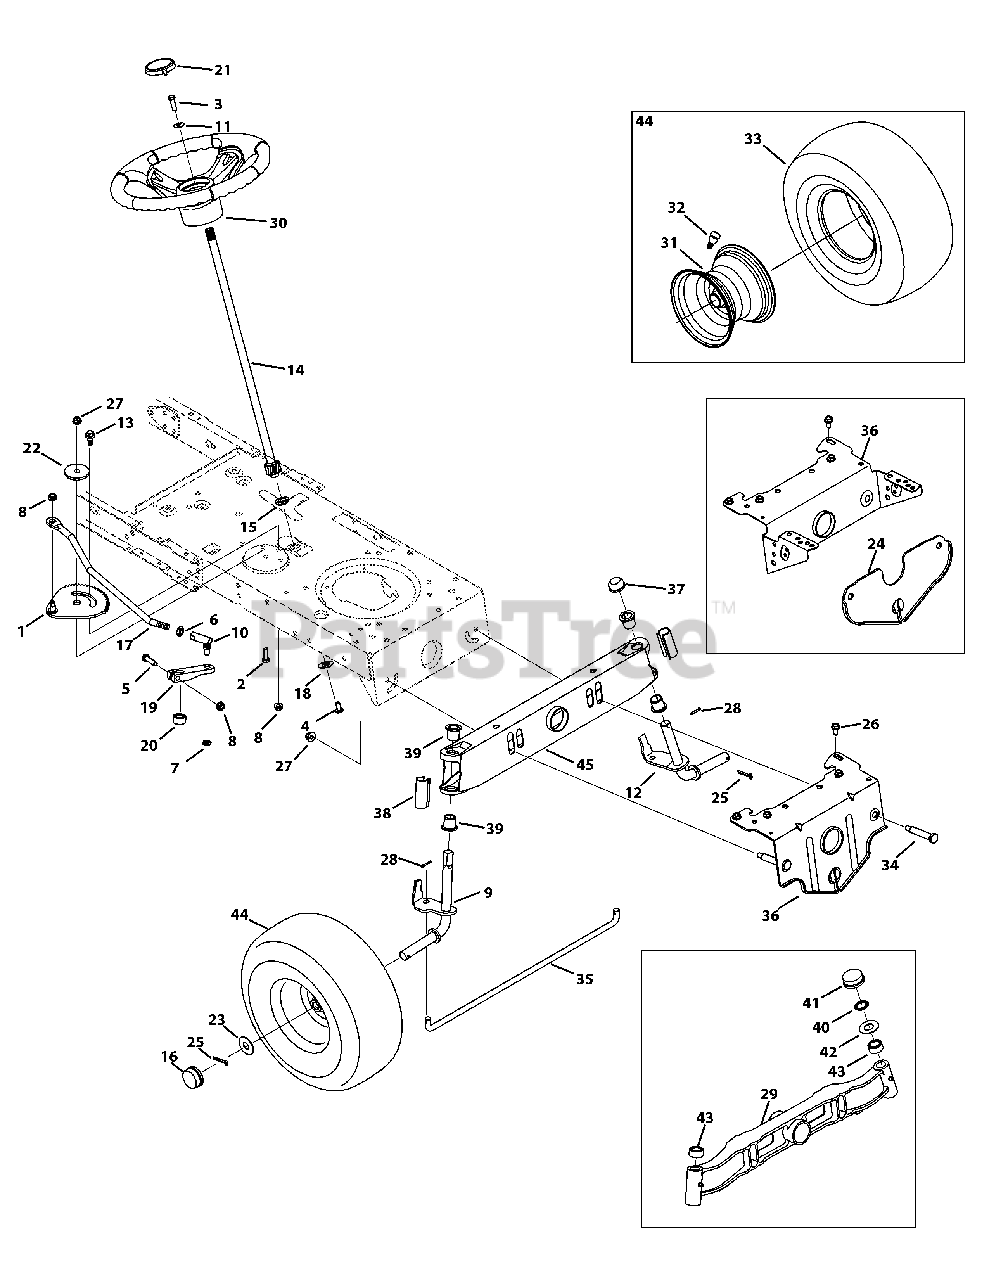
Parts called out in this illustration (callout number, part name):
1	Front Steering Gear Assembly
2	Hex Screw, 3/8-16 x 1.00
3	Hex Screw, 5/16-18 x 1.00, Lock
4	Machine Screw, 5/16-18 x .750
5	Hex Screw, 5/16-18 x 1.75
6	Jam Nut, 7/16-20
7	Jamlock Nut, 3/8-24
8	Flangelock Nut, 5/16-18
9	Axle, Front RH
10	Ball Joint, 7/16-20
11	Bell Washer, .340 x .872 x .060
12	Axle, Front LH
13	Shoulder Bolt, 5/16-18 x .435 x .350
14	Steering Shaft, 5/8 x 22.08
15	Flange Bearing, 5/8
17	Steering Link
18	Cap, 1.25 x .16
19	Steering Block
20	Spacer, .71 x .125 x .56
21	Cap, Troy-Bilt
22	Shoulder Spacer, .884 x .190
23	Flat Washer, .781 x 1.590
24	Front Deck Hanger Bracket
25	Cotter Pin, 5/32 x 1.25
26	Screw, 5/16-18 x .750
27	Flangelock Nut, 3/8-16
28	Cotter Pin, .125 x .75
29	Pivot Axle, Cast Iron
30	Steering Wheel
31	Rim, 6.0 x 4.5
32	Valve, tubeless Air
33	Tire, 15 X 6 X 6 Sq Shoulder
34	Shoulder Bolt, 3/8-16 x .500 x 2.38
36	Pivot Bar Bracket, pointed
37	Push Cap, 3/4
38	Standard Axle Cap
39	Flange Bearing, .760 x .941 x 1.0
40	Push Nut, 3/4
42	Flat Washer, .78 x 1.59 x .060
43	Spacer, .71 x .125 x .56
44	Wheel Assembly, 42" deck
45	Pivot Axle
